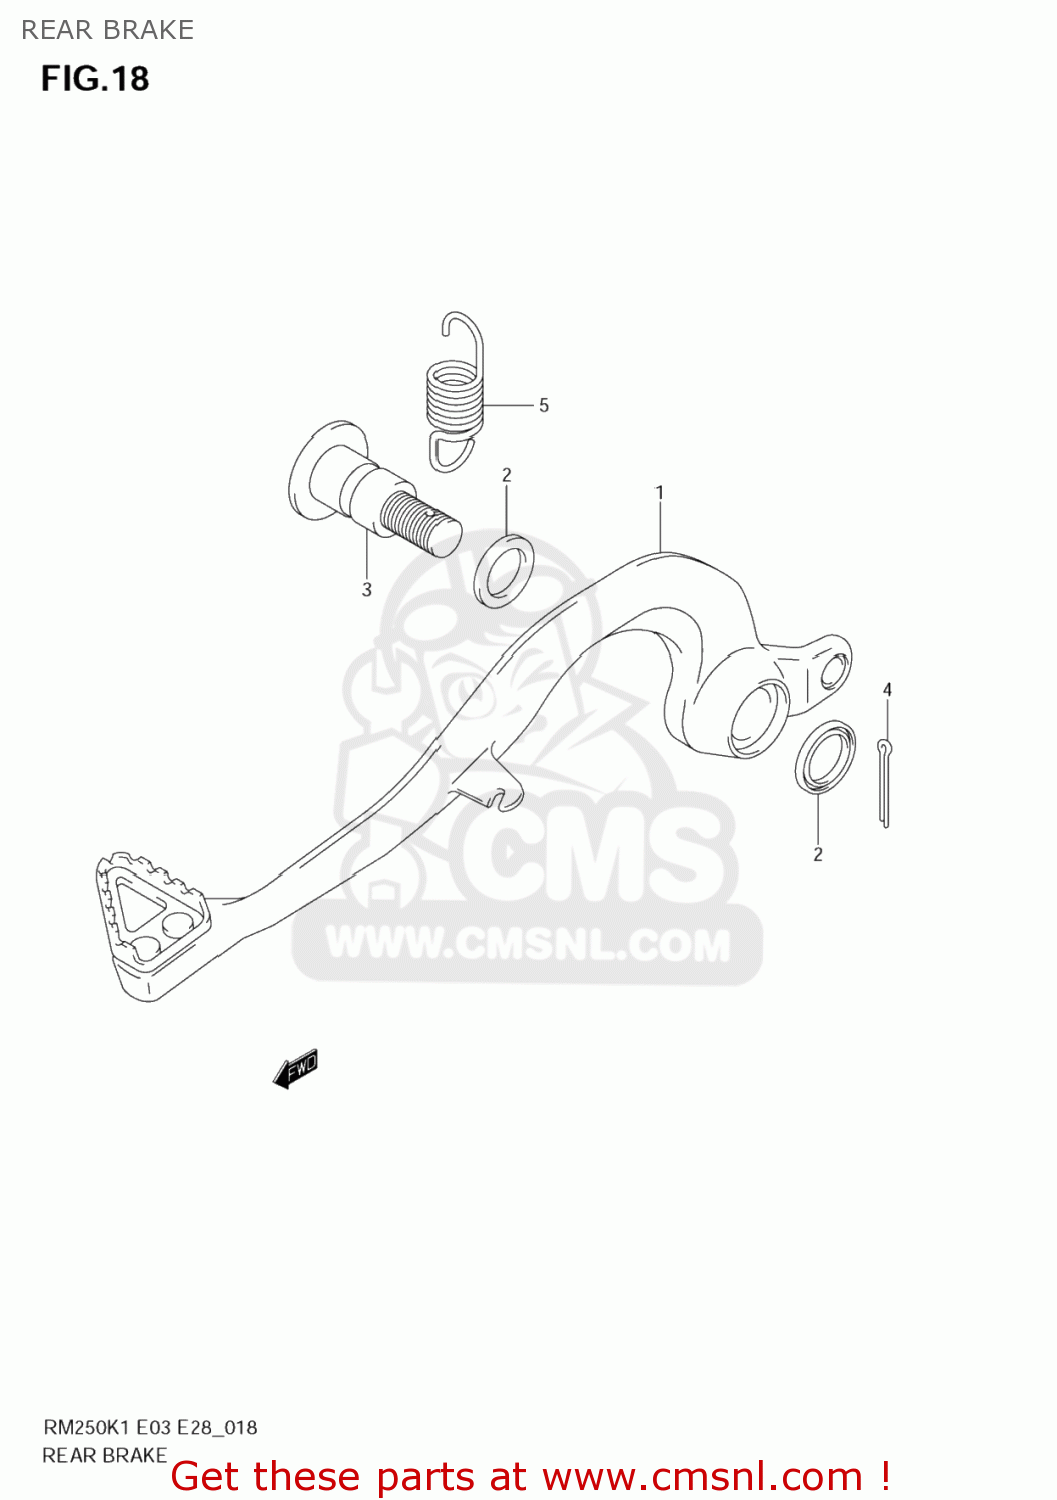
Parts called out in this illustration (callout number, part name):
1	PEDAL ASSY,BRAKE
2	SEAL,OIL(15X21X3)
3	SHAFT,BRAKE PEDAL
4	PIN 20X20
5	SPRING
